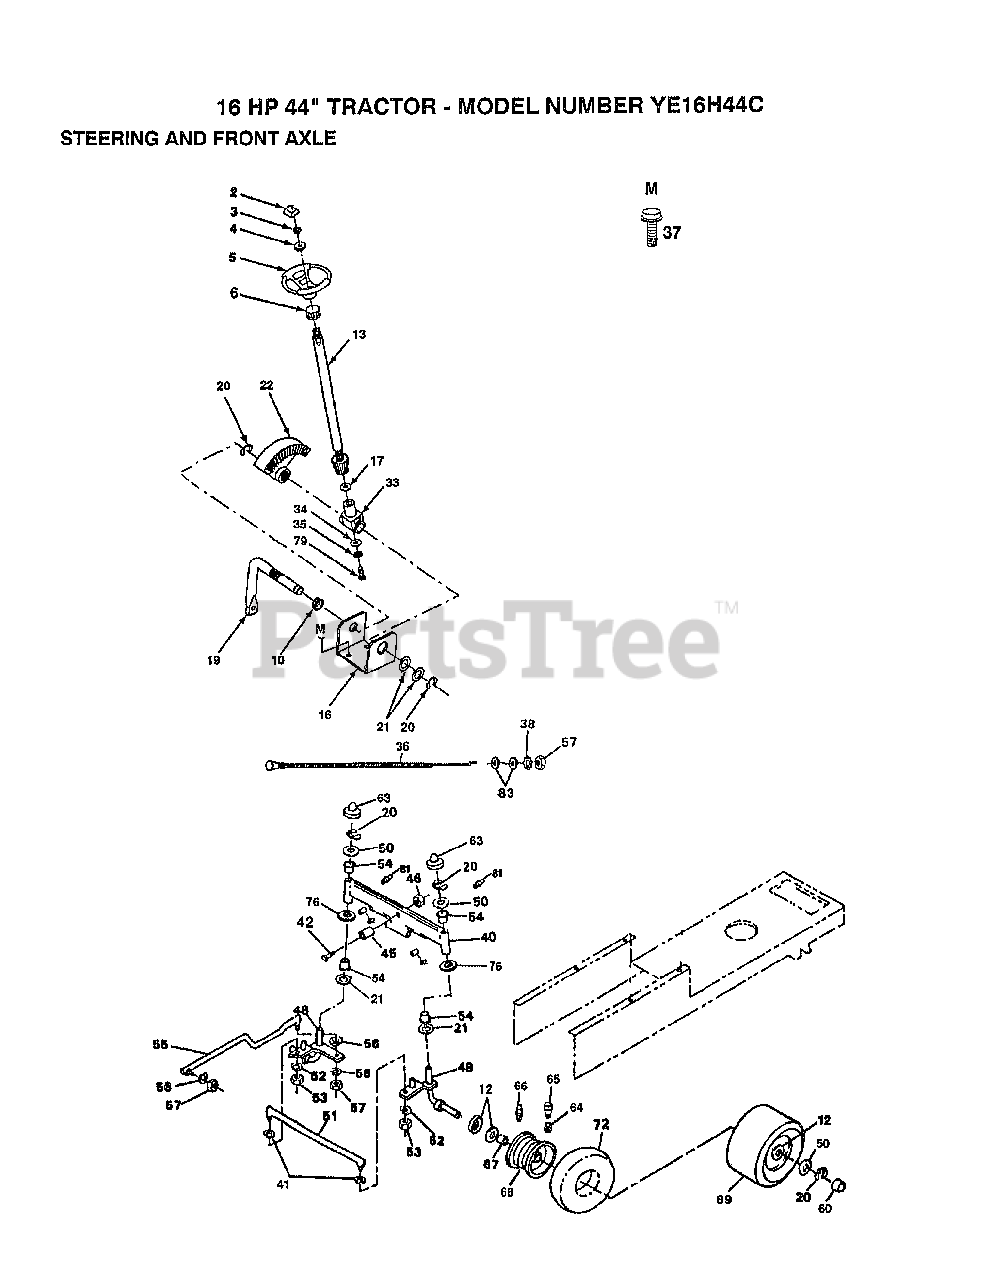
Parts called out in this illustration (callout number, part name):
1	PLUG BUTTON T
2	INSERT STEERING
4	WASHER
6	ADAPTER LT
10	NYLINER T
12	WASHER
16	"BRKT,STEERING"
17	THRUST WASHER
20	RING
21	WASHER .T
33	SUPPORT.SHAFT
35	LOCKWASHER
36	CHOKE CONTROL
37	SCREW
38	LOCKWASHER
40	FRONT AXLE
41	WASHER M
42	BOLT HEX 5/8-11
45	BEARING
48	SPINDLE LH
49	SPINDLE RH
50	WASHER
51	TIE ROD
52	LOCKWASHER
53	NUT.LOCK.5/16-24
54	COL. SRTG. BEAR.
56	LOCKWASHER
60	HUB CAP
63	CAP
64	VALVE CAP
65	VALVE STEM LT
66	FITTING LT
67	"FLANGE, BEARING"
72	TUBE.5.3/4.5/6
76	WASHER
79	"SCREW,SPECIAL"
81	ZERK M
82	AXLE PIN
83	WASHER
